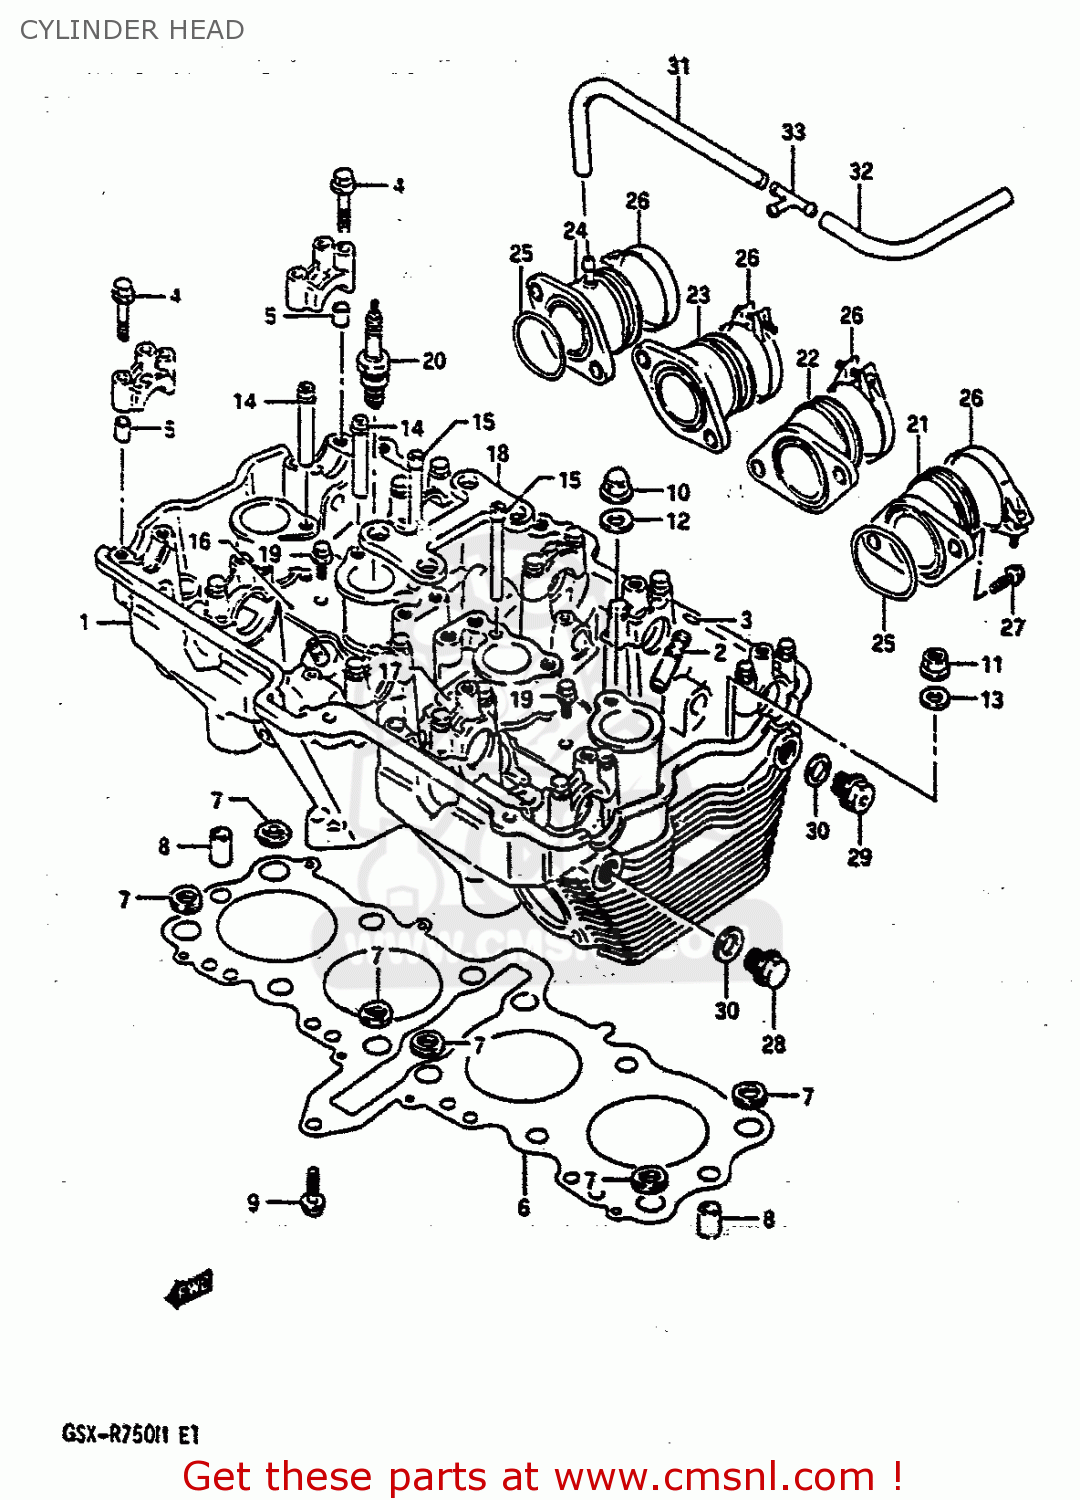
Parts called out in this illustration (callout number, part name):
1	HEAD ASSY,CYLINDER
2	GUIDE,VALVE
3	RING,SNAP
4	BOLT(6X39)
5	PIN(6.2X8X11)
6	GASKET,CYLINDER HEAD
7	O RING,HEAD GASKET
8	PIN
9	BOLT 6X30
10	NUT
11	NUT
12	GASKET(10.2X20X2).3 (NAS)
13	WASHER (10.5X22X2.3)
14	PIPE,OIL NO.1
15	PIPE,OIL NO.3
16	PLATE,OIL PIPE,R
17	PLATE,OIL PIPE,L
18	PLATE,HEAD REINF
19	BOLT
20	PLUG,SPARK(CR9EK)
21	PIPE,INTAKE NO.1
22	PIPE,INTAKE NO.2
23	PIPE,INTAKE NO.3
24	PIPE,INTAKE NO.4
25	O RING(D:2.4,ID:41.7)
26	CLAMP
27	SCREW
28	PLUG
29	PLUG
30	GASKET(14X19.2X2) (NAS)
31	HOSE
32	HOSE
33	JOINT,3 WAY
